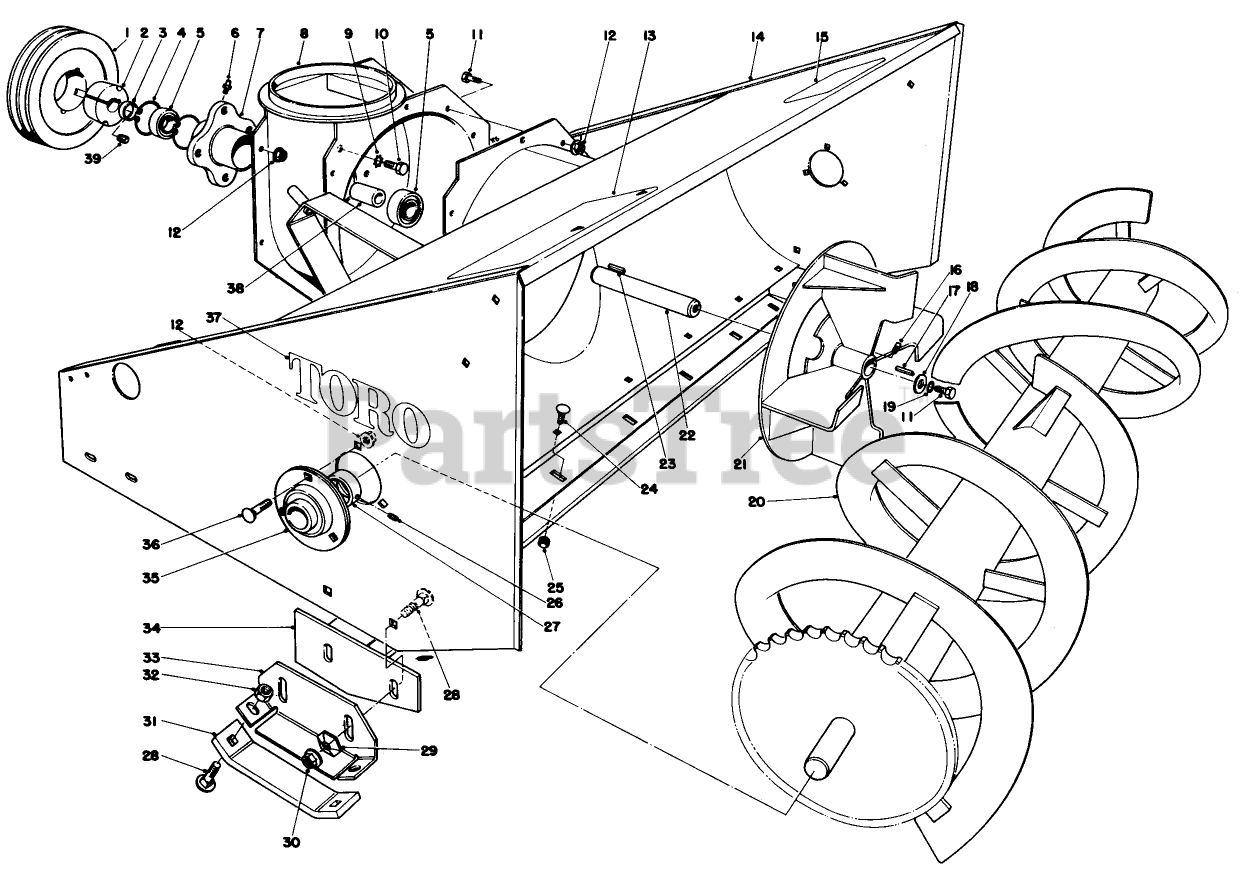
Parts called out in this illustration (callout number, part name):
1	TAPERLOCK PULLEY
2	Taper Lock Bushing
3	SPACER
4	RETAINING RING
5	Bearing
6	FITTING-LUBE, 45 DEG
7	SPINDLE HOUSING
8	Blower Housing
9	WASHER-LOCK, EXT
10	SCREW-HH
11	SCREW-HH
12	NUT-HF
13	Decal-Rear Weight
14	Auger Housing
15	Decal-Warning
16	SCREW-SET
17	Square Key
18	WASHER
19	WASHER-LOCK
20	Auger
21	IMPELLER WA 60096
22	IMPELLER SHAFT
23	KEY-SQUARE
24	SCREW-CARR
25	NUT-LOCK, NI
26	SCREW-SET, HSH
27	COLLAR-LOCK, BEARING
28	BOLT-CARR
29	LOCKWASHER-PYRAMID
30	FLANGE NUT W/LG FLG
31	SKID SHOE R
32	NUT-LOCK, SIDE
33	SKID MTG PLT
34	SCRAPER WA
35	Bearing
36	BOLT-CARR
37	DECAL
38	SLEEVE 16107
39	SCREW-SET
